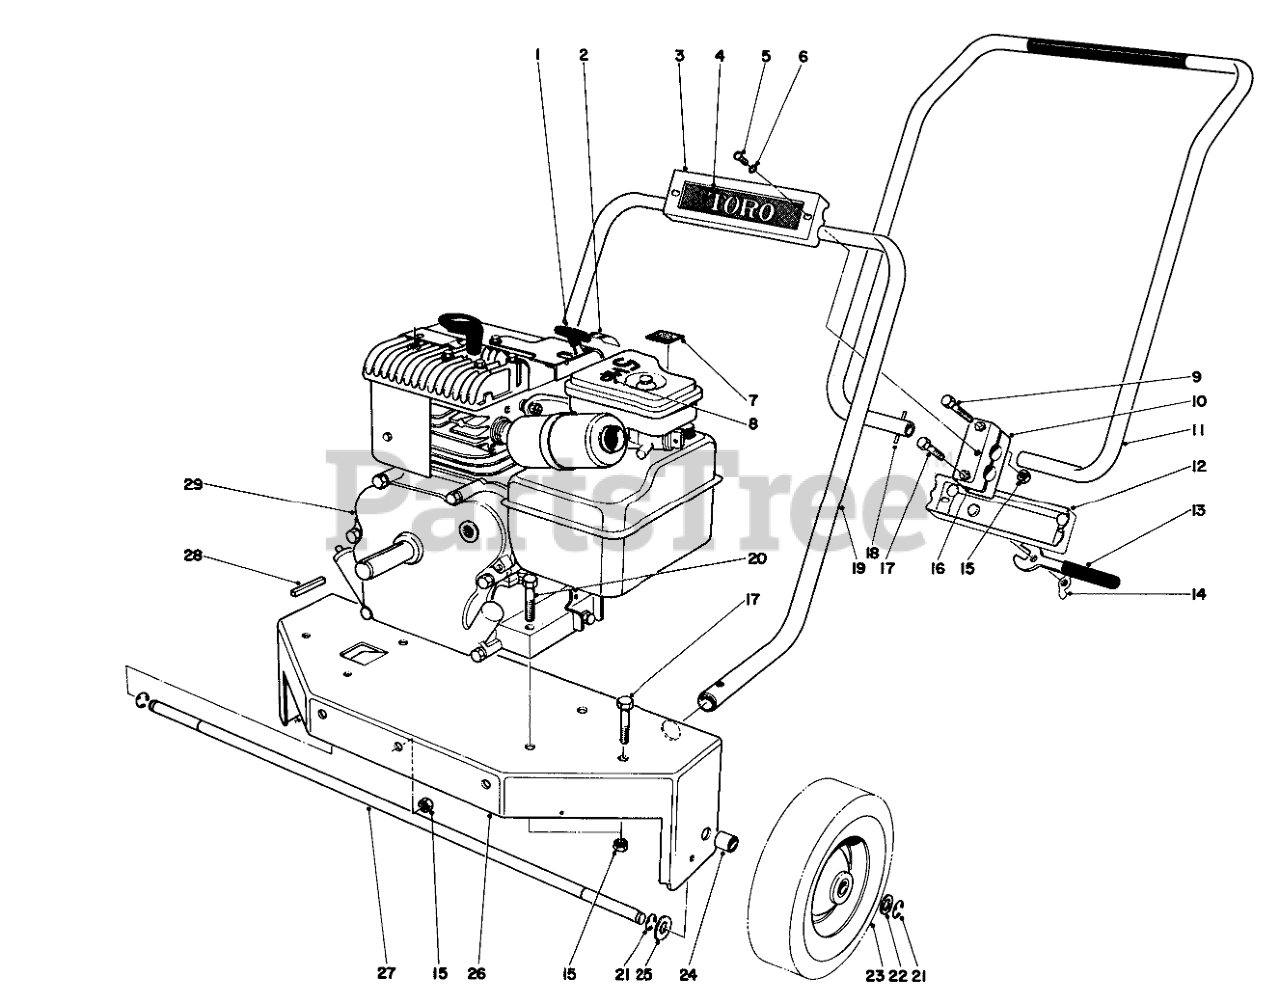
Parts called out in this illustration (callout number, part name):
1	Throttle Control Knob
2	Throttle Decal
3	Front Clamp Cover
4	Decal Toro
5	Screw
6	Washer
7	Caution Decal
8	Decal 5 H.P.
9	SCREW-HH
10	Lower Handle Clamp
11	Upper Handle
12	Rear Clamp Cover
13	Clamp Wrench
14	WING NUT
15	Nut
16	Upper Handle Clamp
17	SCREW-HH
18	Roll Pin
19	Lower Handle
20	SCREW-HH
21	Retaining Ring
22	Washer
23	Wheel & Tire Assy.
24	Spacer
25	WASHER-FLAT
26	Engine Mounting Plate
27	Wheel Axle
28	Key
29	Engine
